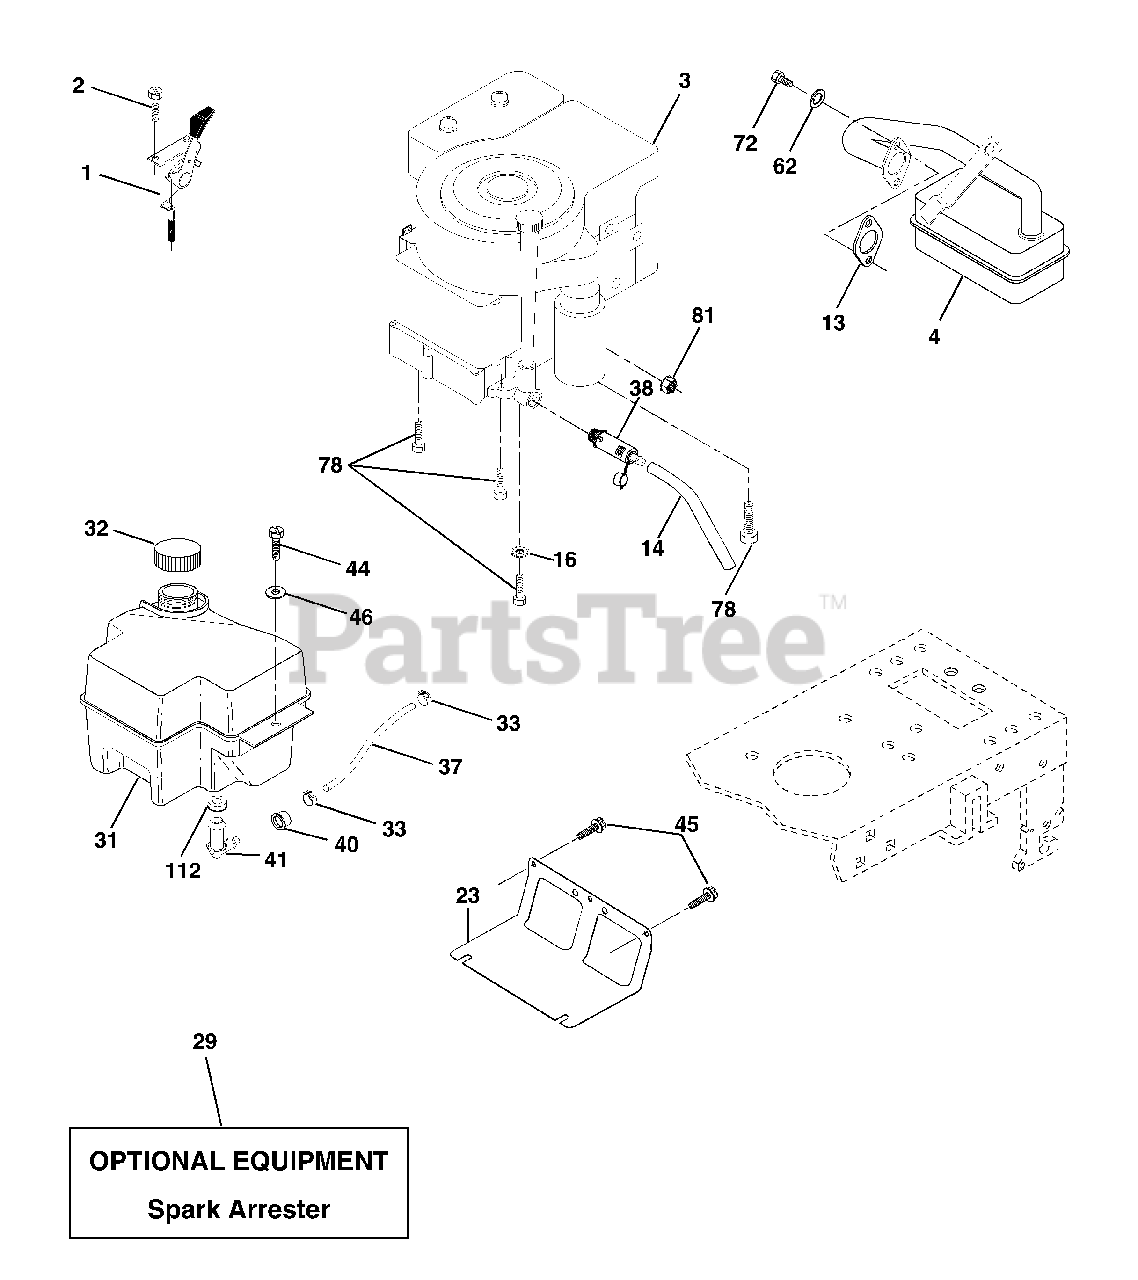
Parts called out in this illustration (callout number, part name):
1	Control Th/ch Flag
2	Screw Hex Thd Cut 1/4-20 1/2
4	Muffler Exhaust
11	Washer Lock 5/16
13	Gasket Muffler
14	Tube Drain Oil Easy
23	Shield Brn/Dbr Guard
29	Arrestor Spark
31	Tank Fuel Front 2 00
32	Cap Fuel
33	Clamp Hose Black
37	Line Fuel 20"
38	Plug Drain Oil Easy
40	Bushing Snap Nyl Blk Fuel Line
41	Stem Tank Fuel
44	Screw Hex wsh Thdrol 1/4-20x3/4
45	Screw Hex Wsh Thdrol 3/8-16 x 3/4
46	Washer 9/32 X 7/8 X 16 Ga
62	Washer Lock Ext Tooth 3/8
72	Screw Hex 5/16-18 x 3/4
78	Screw 3/8-16 x 1-1/4
81	Nut Keps Hex 1/4-20 Unc
112	Bushing
